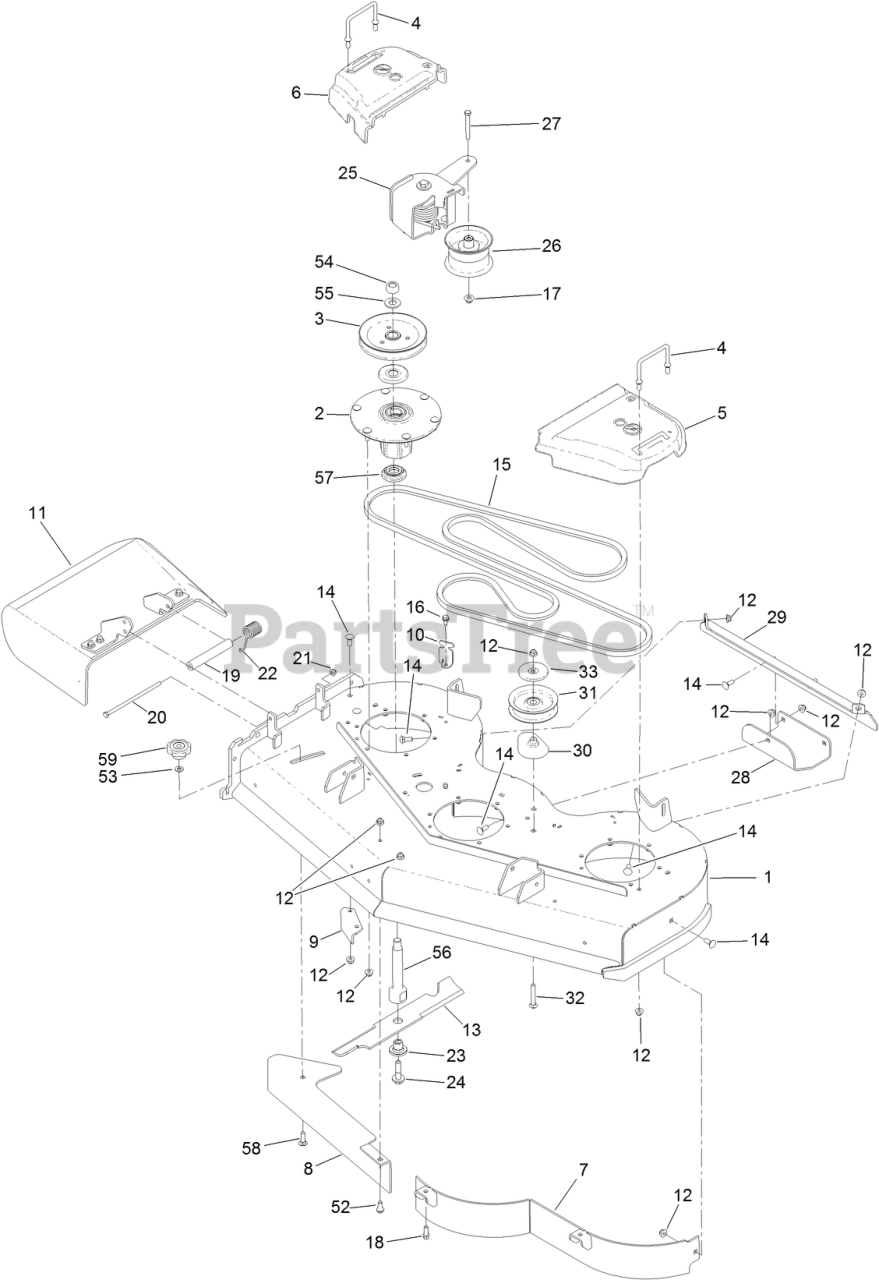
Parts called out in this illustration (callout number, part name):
1	48 DECK ASM
2	SPINDLE ASM
3	SHEAVE-BLADE, DRIVE
4	WIREFORM-COVER
5	COVER-BELT, LH
6	COVER-BELT, RH
7	48 INCH BAFFLE ASM
8	PLATE-BAFFLE, FORMED [RED]
9	BAFFLE-DISCHARGE
10	BRACKET-COVER
11	DEFLECTOR ASM
12	NUT-HF, NI
13	BLADE-16.50 HIGH FLOW
14	BOLT-CARR
15	BELT-V
16	SCREW-HWHTF
17	NUT-FLANGE, NI
19	SPACER
20	SCREW-HH
21	NUT-HF, NI
22	SPRING-TORSION
23	BUSHING-HEX
24	SCREW-SEMS
25	GS TORSION IDLER ASM II
26	PULLEY-IDLER
27	SCREW-HH
29	BRACKET-SKID
30	SPACER-PULLEY
31	PULLEY-IDLER, FLAT
32	SCREW-CARR
33	SHIELD-DUST
52	BOLT-SHOULDER
53	WASHER-HARDENED
54	NUT-HEX
55	WASHER
56	SHAFT-SPINDLE
57	GUARD-BOTTOM
58	BOLT-CARR
